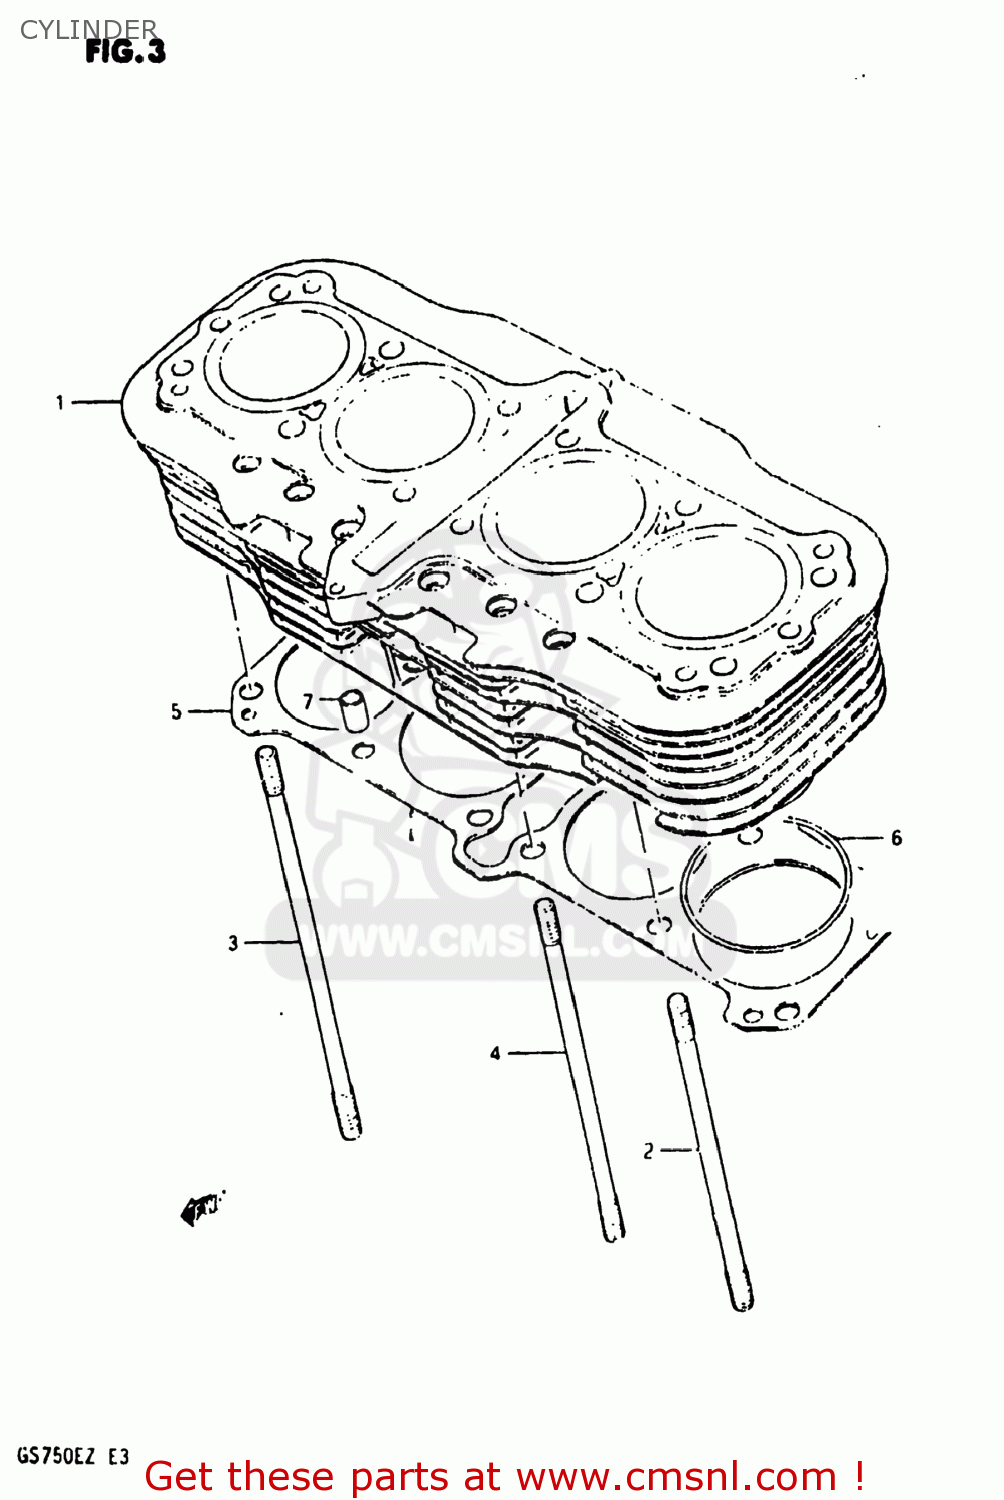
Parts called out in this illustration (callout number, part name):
1	CYLINDER
2	STUD
3	STUD
4	STUD
5	GASKET,CYLINDER (MCA)
6	O RING(D:2,ID:70)
7	PIN
